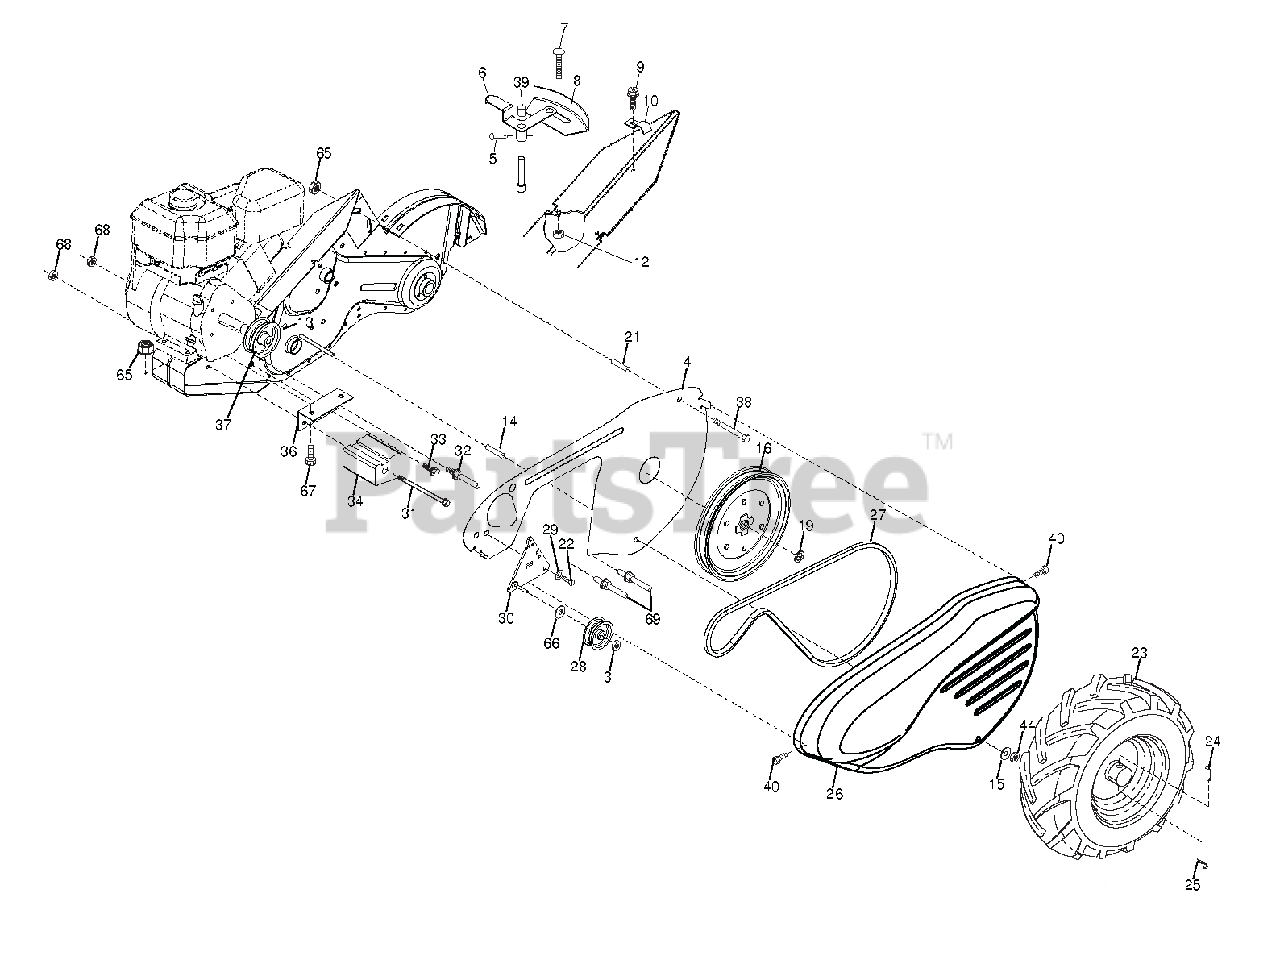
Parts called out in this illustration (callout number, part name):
3	NUT.CENTERLOCK.3/8-16 UNC.
4	SHIELD, INNER BELT GUARD
5	Pin, Shift Lever
6	Lever, Shift
7	Bolt 1/4-20 unc x 1/2 Gr. 5
8	Plate, Shift Indicator
9	Screw, Tap Hex Head
10	Clip, Cable
12	Nut, Keps Hex 1/4-20 unc
13	Screw Set 5/16-18 x 3/8 Patch
14	Spacer, Split .327 x .42 x 2.0
15	Washer 11/32 x 11/16 x 16 Ga.
16	Sheave, Transmission
19	Ring, Retainer
21	Spacer, Split .327 x .42 x 1.2
22	Bolt, Hex Head 5/16-24 unf x 1
24	Rivet, Drilled
25	RETAINER SPRING
26	GUARD, BELT
27	Belt, V
28	Pulley, Idler
29	Ring, Klip
30	Bracket, Idler
31	Bolt, Hex 5/16-16 x 12
32	Shaft, Idler Arm
33	Bolt, Hex 3/8-16 x 1
34	Counterweight, LH
36	Bracket, Reinforcement, LH
37	Sheave, Engine
38	Bolt, Fin Hex 5/16-18 x 2-3/4
39	Cap, Plunger
40	Screw Hex Wsh Hd #8-18 x 1/2
44	Locknut, Washer Insert 5/16-18
65	Nut, Hex, Flangelock
66	Washer 13/32 x 13/16 x 12 Ga.
67	Bolt, Hex Head, Gr. 25/16-18 x
68	Nut Keps Hex 3/8-16 unc
69	KEEPER BELT ENGINE
